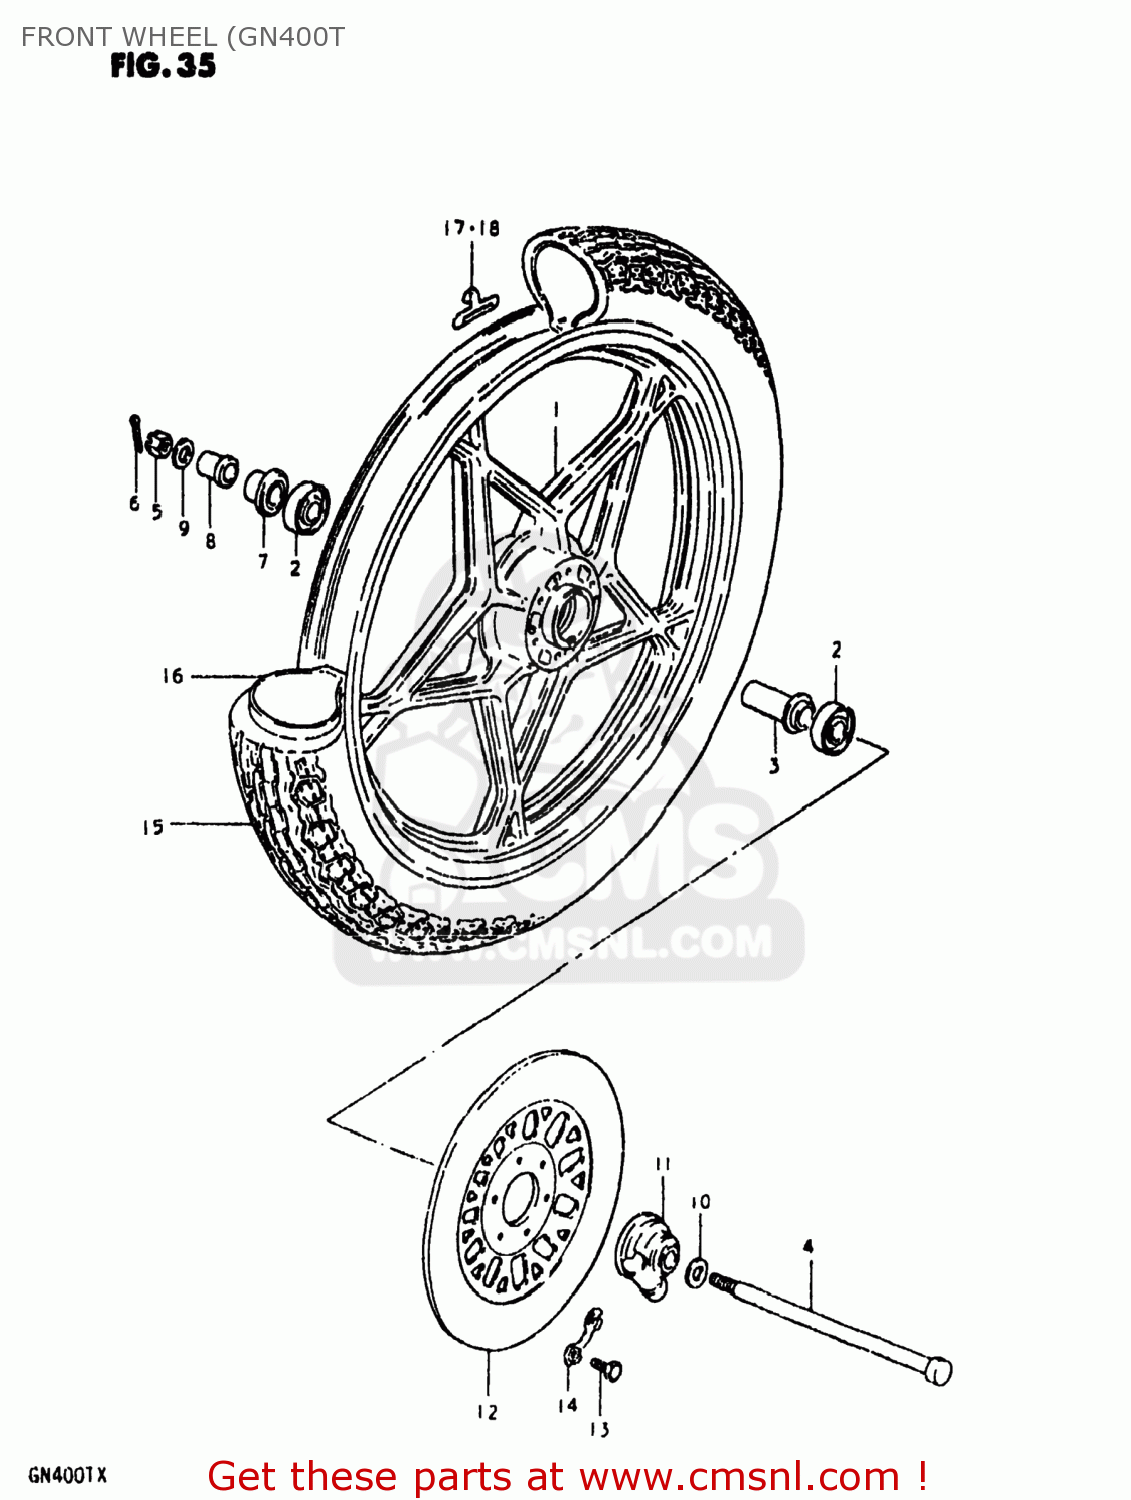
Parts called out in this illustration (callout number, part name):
2	BEARING
3	SPACER,FR HUB BEARING
4	AXLE,FR
5	NUT 12MM
6	COTTER PIN
7	SPACER,FR AXLE,R
8	SPACER
9	WASHER
10	WASHER(15.5X26X2.3)
11	BOX ASSEMBLY,SPEEDOMETER GEAR
12	DISC,FR BRAKE
13	BOLT(8X25)
14	WASHER
15	TIRE,FRONT
16	TUBE,INNER
17	BALANCER,WHEEL
18	BALANCER,WHEEL
